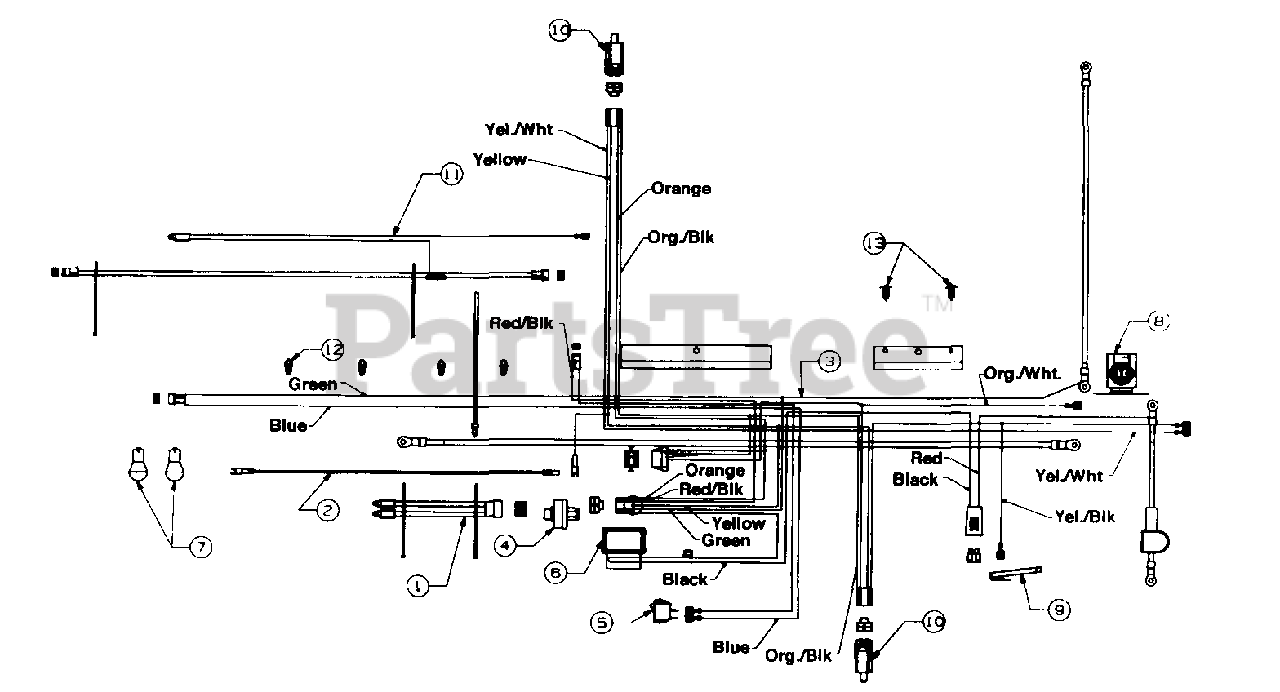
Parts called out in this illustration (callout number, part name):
1	Wire Harness (Monitor)
2	Harness Adapter
3	Wire Harness w/Light Switch, Amp and Monitor
4	Ignition Switch
5	Light Switch
6	Ammeter
7	Bulb
8	Solenoid
9	Safety Switch (Reverse)
10	Safety Switch
11	Harness Ass'y. (Oil)
12	Wire Retainer Clip
13	Ratchet
